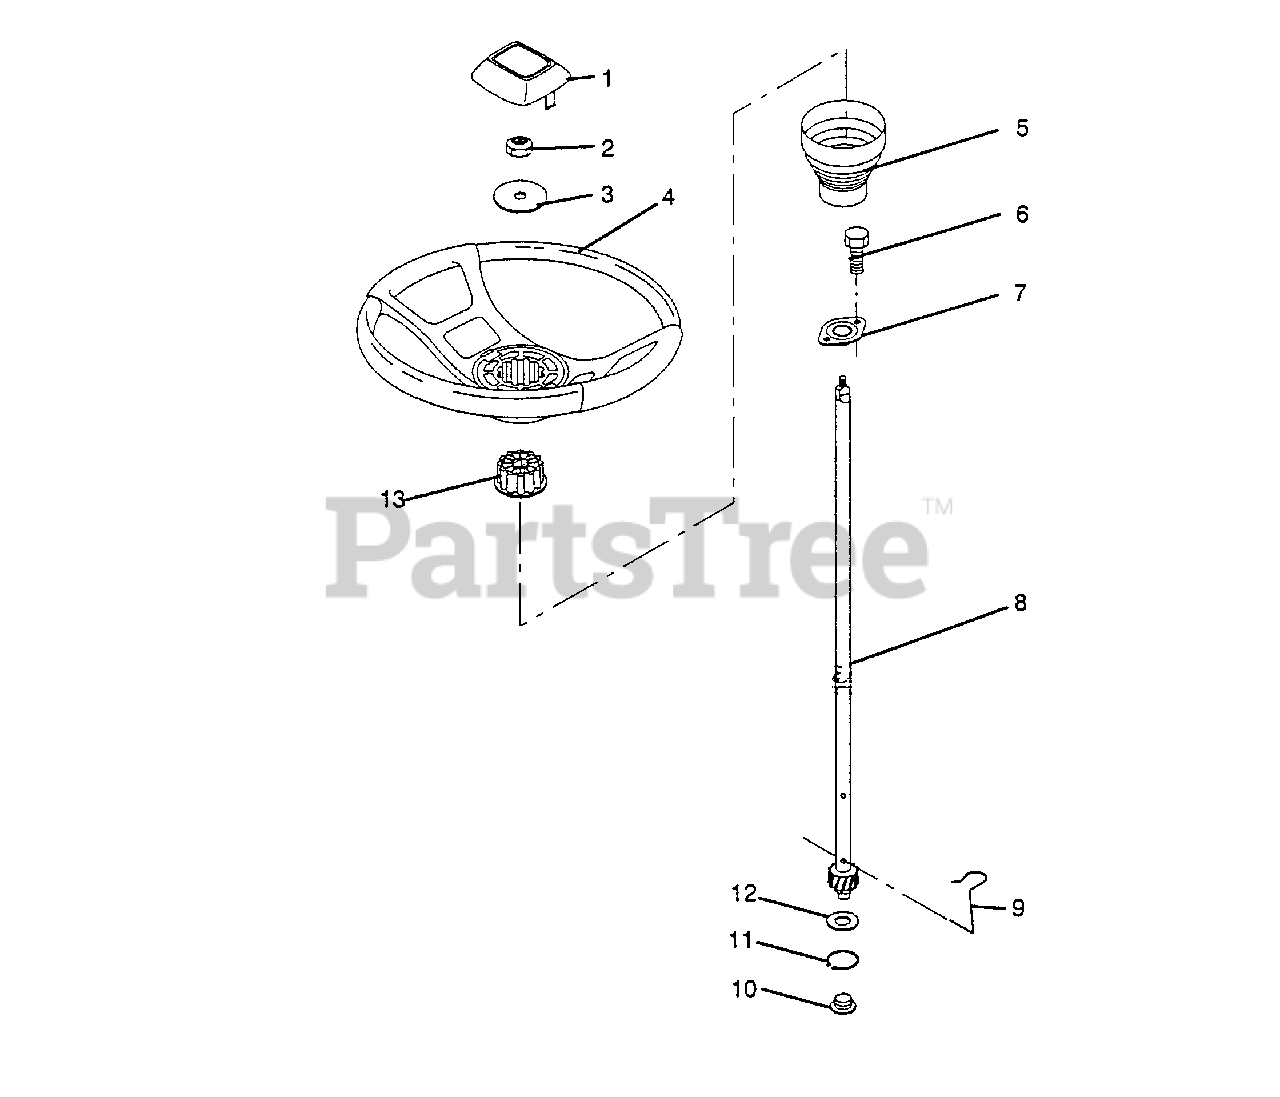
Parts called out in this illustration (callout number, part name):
1	Insert, Wheel, Steering
2	Nut, Lock 3/8-24 UNF
3	Washer 13/32 x 2-3/8 x 8 Ga.
4	Wheel, Steering
5	Sleeve, Steering
6	Screw, Hex SLFTP #10-16 x 1/2 TY-B
7	Bushing, Steering
8	Shaft, Steering
9	Clip, Steering
10	Bushing, Lower, Steering
11	Ring, Retaining
12	Washer 21/32 x 1 x 16 Ga.
13	Adaptor, Wheel, Steering
